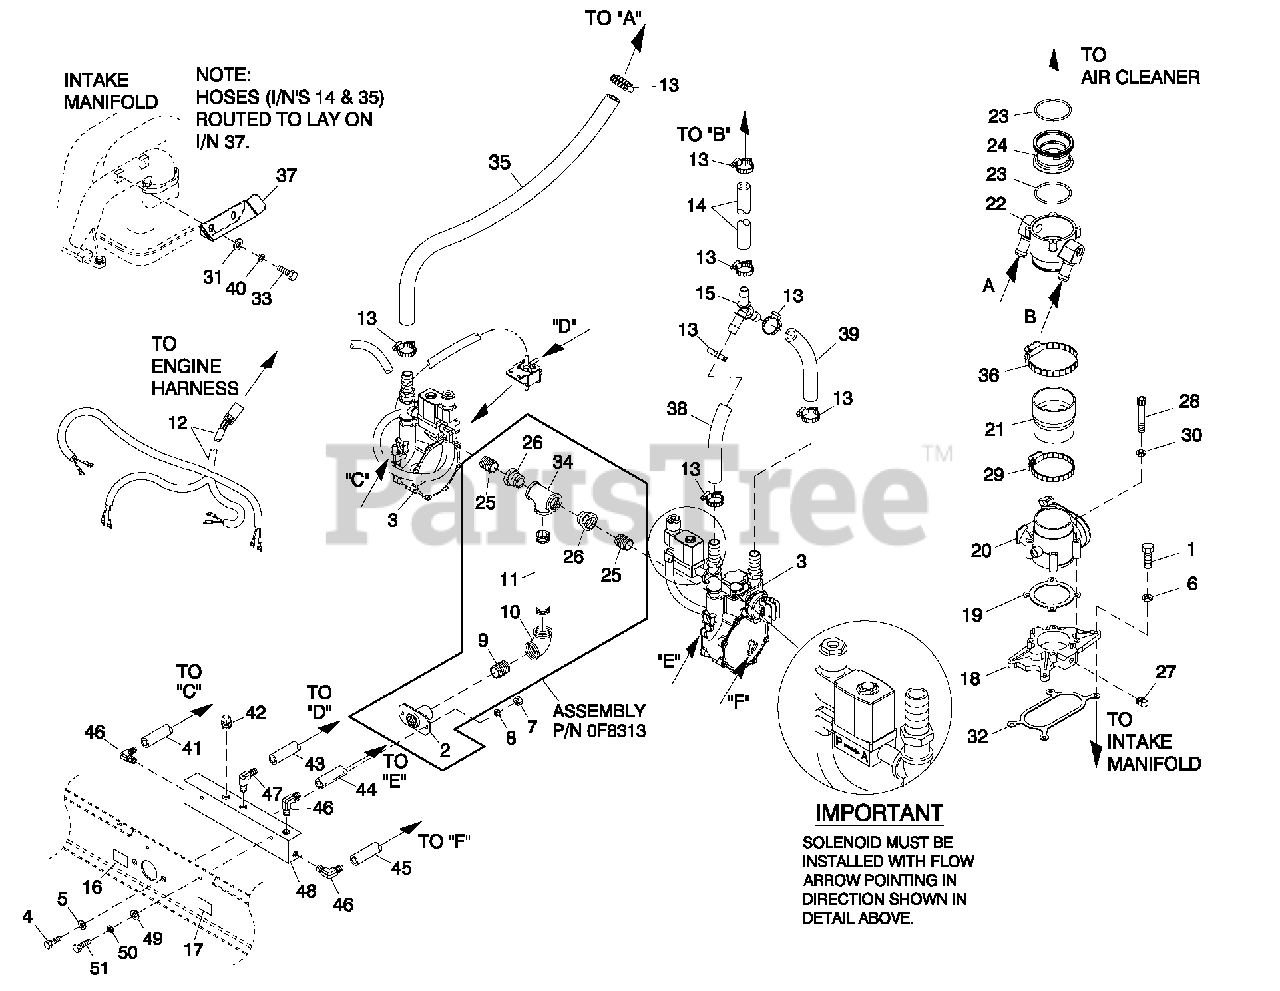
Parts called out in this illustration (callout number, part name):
1	SCREW HHC 5/16-18 X 1-1/4 G5
2	SUPPORT NAT GAS SOLENOID
3	REG 6.8L CPL 100 KW N/G EMISS
4	SCREW HHC M12-1.75 X 20 G8.8
5	WASHER FLAT 1/2 ZINC
6	WASHER LOCK M8-5/16
7	NUT HEX M12-1.75 G8 YEL CHR
8	WASHER LOCK 1/2
9	NIPPLE CLOSE 1.25 NPT X 1.625
10	ELBOW 9 0D 1-1/4 NPT
11	NIPPLE PIPE 1-1/4 NPT X 3
12	HARNESS, FUEL JUMPER DUAL REG
13	CLAMP HOSE #8 .53-1.00
14	HOSE 3/4 ID SAE-30R2 (42" LG)
15	Y CONNECTOR 500 SERIES BARBS
16	DECAL INLET PRESSURE
17	DECAL FUEL INLET NG
18	ASSY,ADAPTER,THROTTLE BODY
19	GASKET GOVERNOR ACTUATOR
20	ACTUATOR BOSCH 60 GOVERNOR
21	REDUCER 3.0" TO 2.75" TURBO
22	MIXER 40/60MM ACTUATOR ASSY
23	O-RING 2-3/4X3/32X2-15/16
24	VENTURI, THROTTLE 42MM
25	NIPPLE CLOSE 3/4X1.375
26	BSHG RDCRHEX1-1/4-3/4
27	PLUG STD PIPE 1/4 STEEL SQ HD
28	SCREW SHC M6-1.0 X 50 C8.8
29	CLAMP HOSE #44 2.31-3.25
30	WASHER LOCK M6-1/4
31	WASHER FLAT M6
32	GASKET ADAPTER THROT BODY
33	SCREW HHC M6-1.0X 20 G8.8
34	PIPE TEE 1-1/4 NPT
35	HOSE 3/4 ID SAE-30R2 (45" LG)
36	CLAMP HOSE #52 2.81-3.75
37	BRACKET, HOSE RISER
38	HOSE 3/4 ID SAE-30R2 (9.5" LG)
39	HOSE 3/4 ID SAE-30R2 (12" LG)
40	WASHER LOCK M6-1/4
41	HOSE VACUUM 5/32 (5"LG)
42	PLUG STD PIPE 1/8 STEEL SQ HD
43	HOSE VACUUM 5/32 (18"LG)
44	HOSE VACUUM 5/32 (6"LG)
45	HOSE VACUUM 5/32 (8"LG)
46	BARBED EL 90 3/16X1/8
47	BARBED EL W/VENT (.052")
48	MANIFOLD, EMISSIONS VACUUM
49	WASHER FLAT 1/4-M6 ZINC
50	WASHER LOCK M6-1/4
51	SCREW HHC M6-1.0X 25 G8.8
